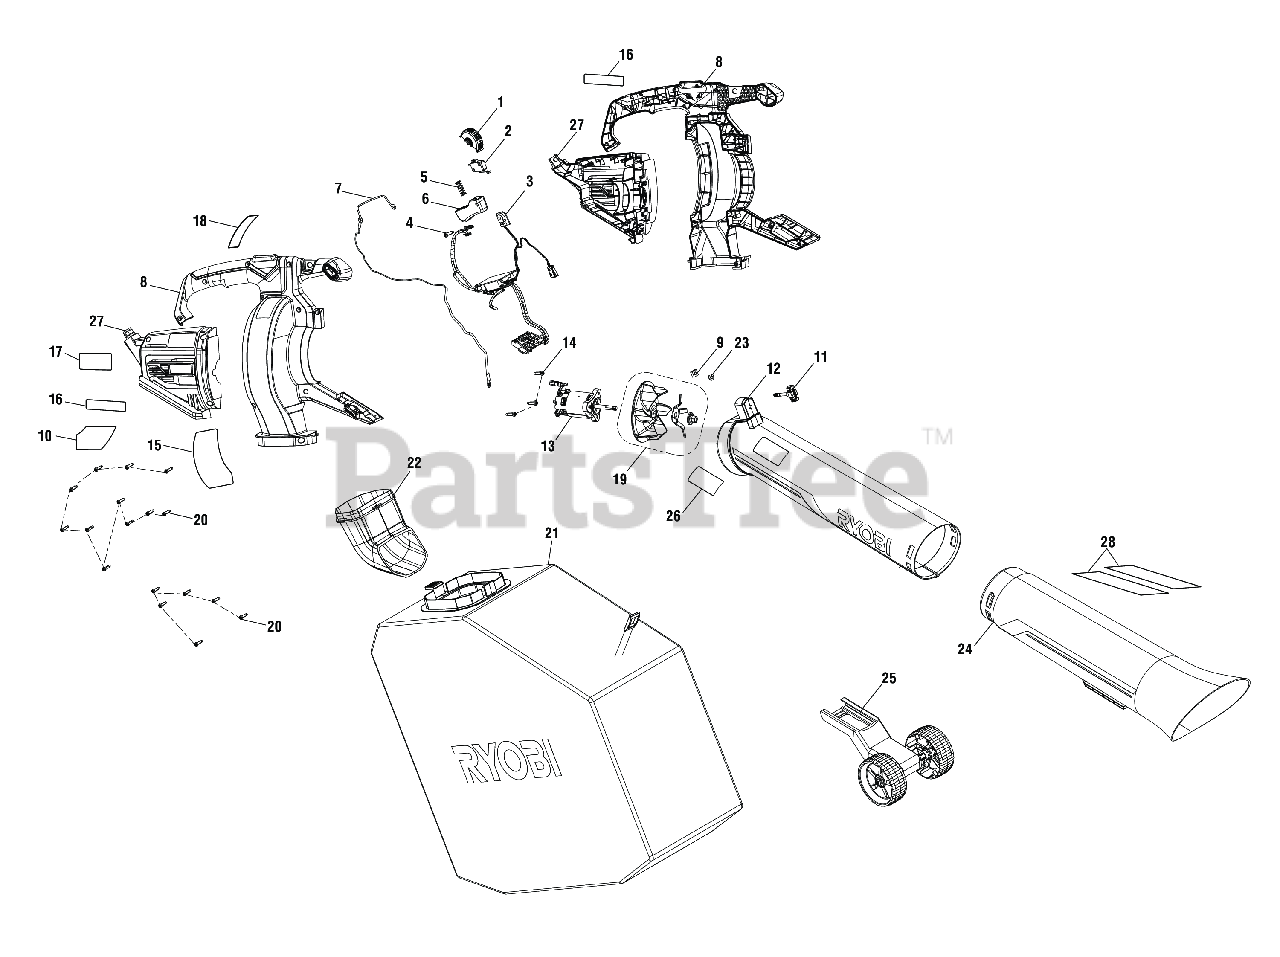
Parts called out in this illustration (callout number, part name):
1	Dial Lever Assembly
2	Switch (Micro)
3	Motor Controller & Battery Holder Assembly
4	SCREW, CH M3 PH B\L=6MM
5	Compression Spring
7	Hand Wire Assembly.
8	Handle Housing Assembly (Inc. Key Nos. 10, 15 & 18)
9	Square Nut (M5)
10	Caution Label
12	Upper Tube Assembly (Inc. Key No. 26)
13	Motor Assembly
14	Screw (T25 x 12 mm, Flange Hd.)
15	Warning Label (French & Spanish)
16	Logo Label
17	Data Label
18	Warning Icon Label
19	Blade Assembly
20	Screw (M4 x 14 mm, T15 Torx Pan Hd.))
21	Bag Assembly
22	Leaf Chute
23	Retaining Ring
24	Lower Tube Assembly (Inc. Key No. 28)
25	Wheel Assembly
26	Start Label
27	Motor Housing Assembly (Inc. Key Nos. 16-17)
28	Vac Attack Label
